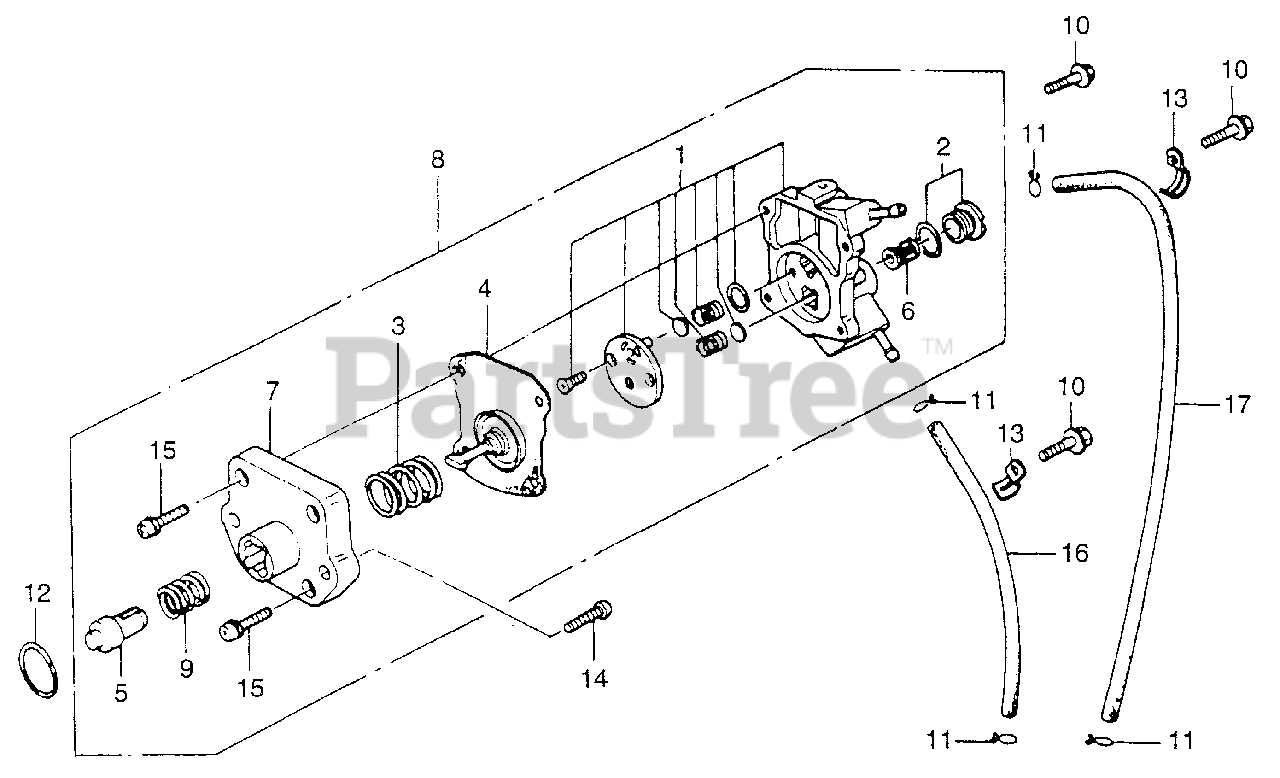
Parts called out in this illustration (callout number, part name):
1	BODY SET, PUMP
2	BOLT SET, HOLDING
3	SPRING, DIAPHRAGM
4	DIAPHRAGM
5	ROD, PUSH
6	SCREEN, FUEL STRAINER
7	BODY (LOWER)
8	PUMP ASSY., FUEL (NOT AVAILABLE)
9	SPRING, PUSH ROD
10	BOLT, FLANGE (6X28)
11	CLIP, TUBE (B8)
12	O-RING (20.8X2.4)
13	CLIP, WIRE
14	SCREW, PAN (6X20)
15	SCREW-WASHER (4X16)
16	BULK HOSE, FUEL (4.5X3000) (4.5X320)
17	BULK HOSE, FUEL (4.5X3000) (4.5X400)
